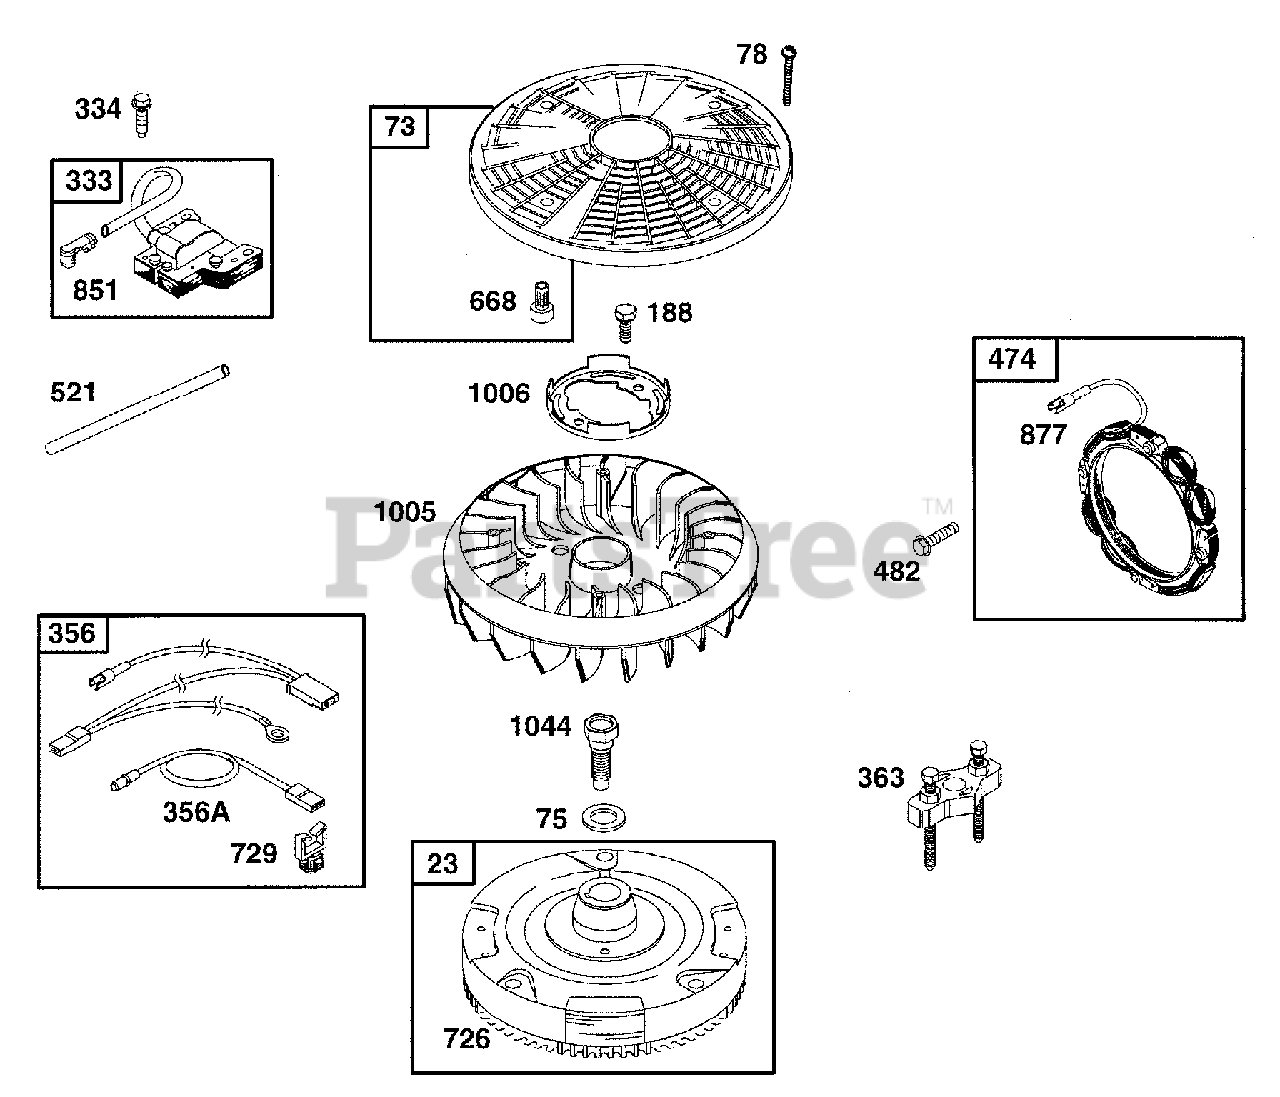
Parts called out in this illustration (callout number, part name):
23	Flywheel
73	Rotating Screen
75	Flywheel Washer
78	Torx Screw
188	Hex Screw
333	Magneto Armature
334	Hex Screw
356	Wiring Harness
363	Flywheel Puller
474	Alternator
482	Hex Screw
521	Cable Shielding
668	Spacer
726	Ring Gear
851	Cable Terminal
877	Alternator Wire
1005	Flywheel Fan
1006	Fan Retainer
1044	Shoulder Screw
